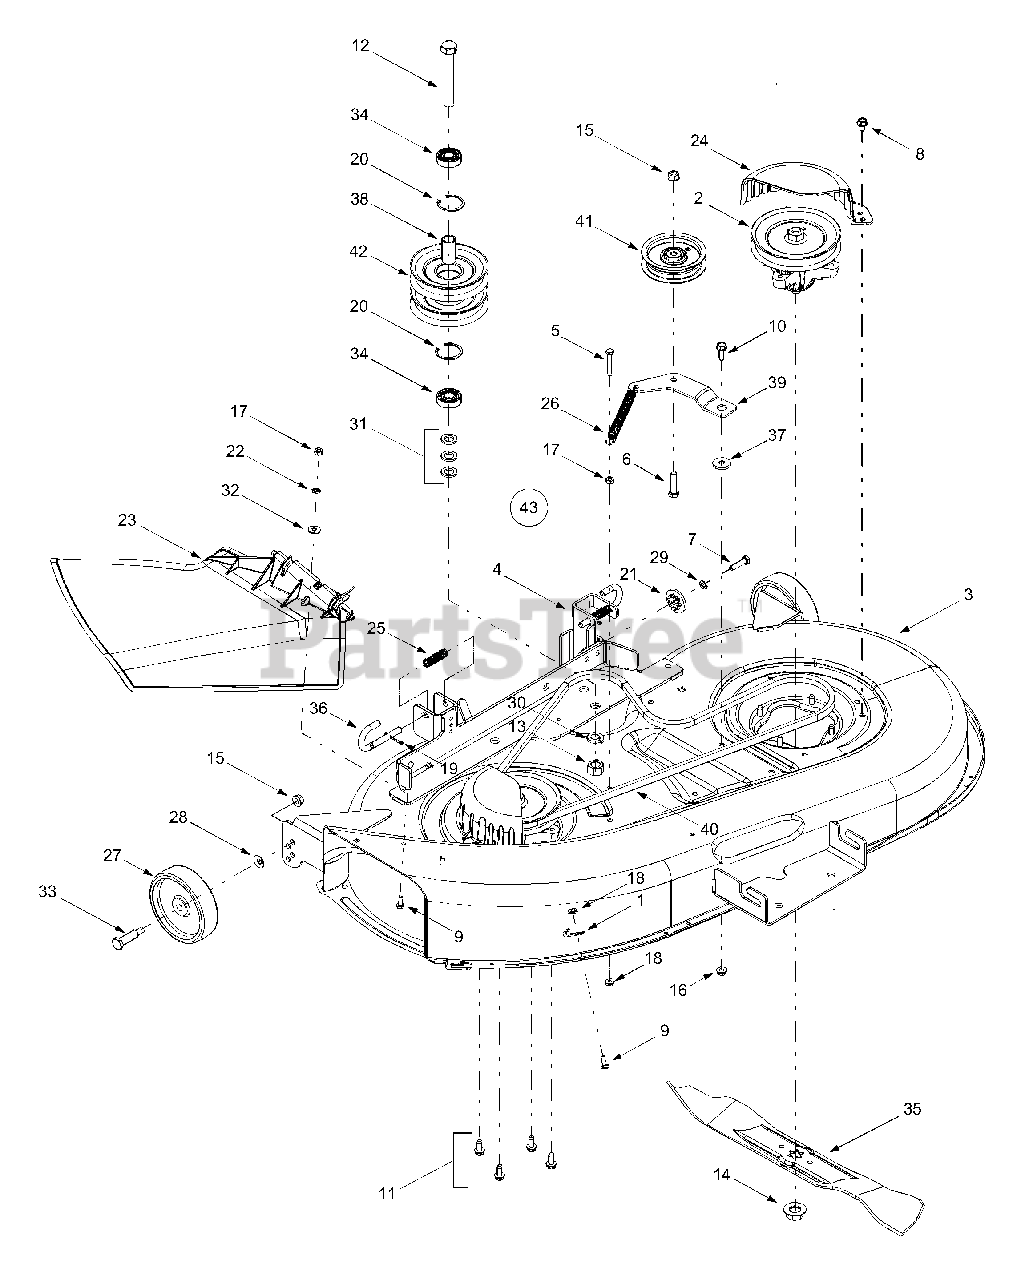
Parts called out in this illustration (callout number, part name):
1	Retainer Hook
2	Spindle Assembly, 5.75 Dia. w/ Fitting
2	Pulley Only
5	Hex Cap Screw, 1/4-20 x 1.75
6	Hex Cap Screw, 1/4-20 x 1.5
7	Hex Cap Screw, 5/16-18 x 1.25
8	Self-tapping Screw, 5/16-18 x .625
9	SCREW 1/4-20 x .620 GR5
10	Hex Head Washer Screw, 5/16-18 x .875
11	Self-tapping Screw, 5/16-18 x .75
12	Hex Cap Screw, 5/8-18 x .875
13	Hex Nut, 5/8-18
14	HEX NUT
15	Flange Lock Nut, 3/8-16
16	HEX FLANGE NUT
17	HEX NUT
18	Hex Flange Lock Nut, 1/4-20
19	Cotter Pin, 1/8 x 1.25
20	Internal Snap Ring
21	Deck Adjustment Gear
22	Push Nut. .25 x .5
23	Side Discharge Chute Assembly
24	Belt Cover
25	Compression Spring, .406 x .531 x 1.75
26	Extension Spring, .50 x 4.74
27	PLASTIC WHEEL 5X1.38
28	Bell Washer, .401 x .87 x .063
29	Lock Washer, 5/16
30	Lock Washer, 5/8
31	Flat Washer, .64 x 1.0 x .12
32	SPRING WASHER BELL
33	Shoulder Screw, .498 x 1.53
34	Bearing, .625 x 1.574 x .470
35	Three-in-one Blade, Star Center, 21.23"
36	Deck Release Pin
37	Shoulder Spacer, .625 x .324
38	Spacer, .635 x .88 x 1.72
39	Idler Bracket
40	Deck Belt
41	Idler Pulley, 3.5
42	Double Pulley, 5.0
